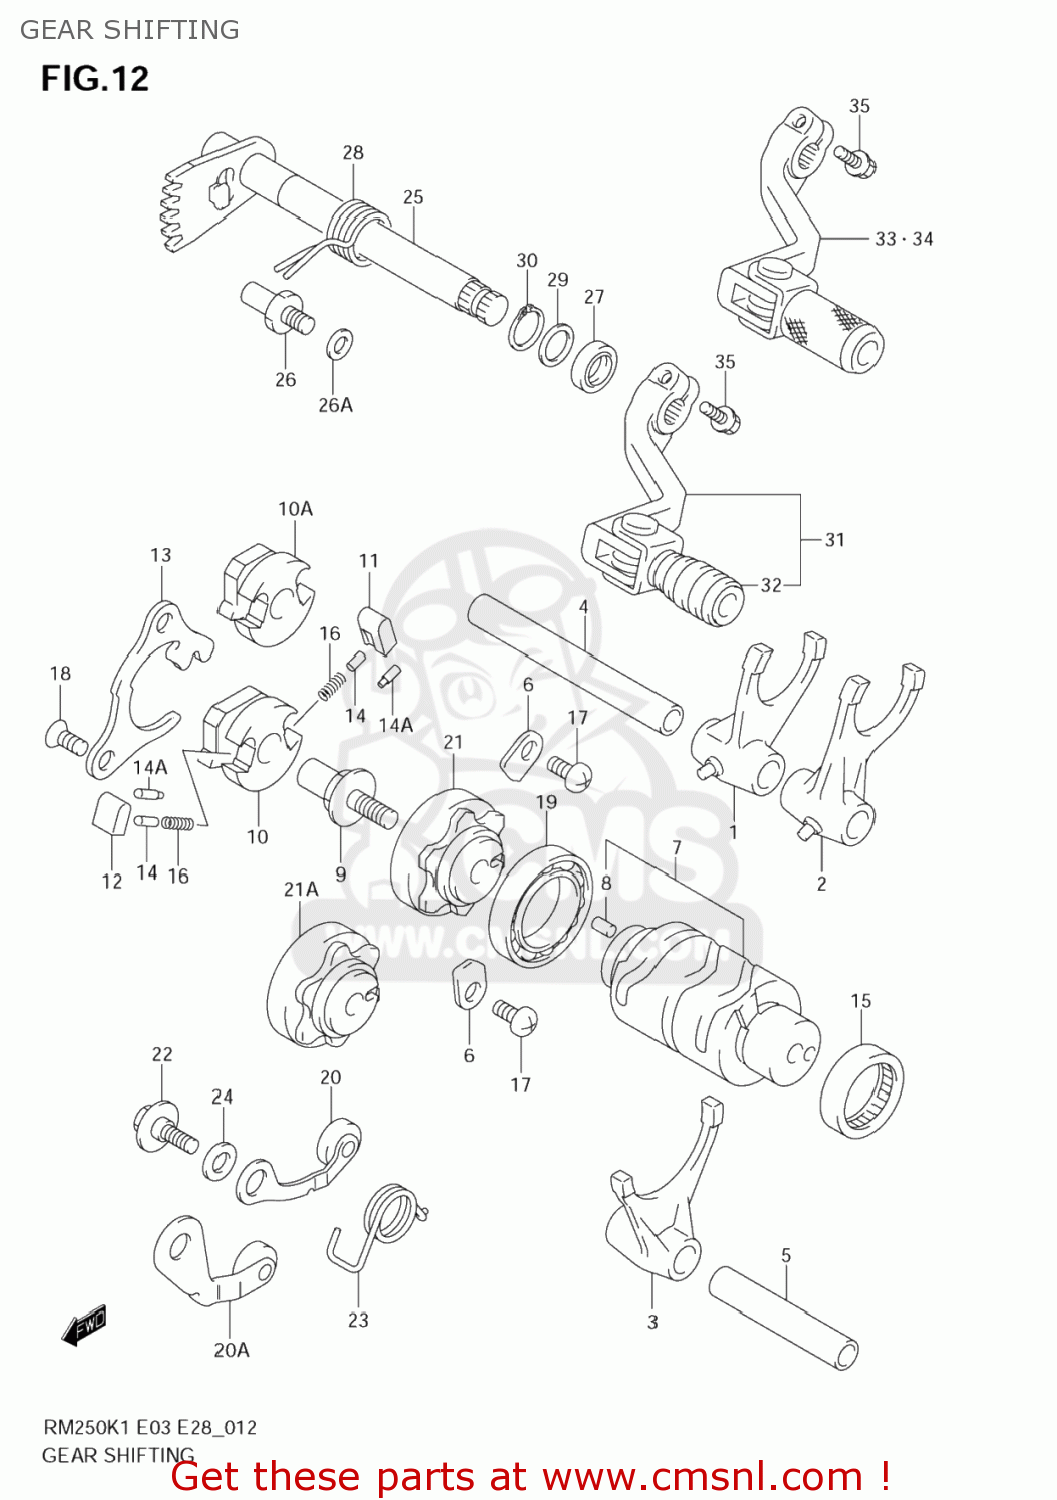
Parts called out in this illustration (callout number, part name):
1	FORK,GEAR SHIFT NO.1
2	FORK,GEAR SHIFT NO.2
3	FORK,GEAR SHIFT NO.3
4	SHAFT,GEAR SHIFT FORK
5	SHAFT,GEAR SHIFT FORK(L:60)
6	RETAINER
7	CAM,GEAR SHIFT
8	PIN
9	PIN,GEAR SHIFT CAM
10	GEAR,GEAR SHIFT CAM DRIVEN
10A	GEAR,GEAR SHIFT CAM DRIVEN
11	PAWL,GEAR SHIFT NO.1
12	PAWL,GEAR SHIFT NO.2
13	LIFTER,GEAR SHIFT PAWL
14	PIN(5X8)
14A	PIN
15	BEARING(25X32X12)
16	SPRING
17	BOLT(6X12)
18	SCREW
19	BEARING
20	STOPPER,SHIFT CAM
20A	STOPPER,SHIFT CAM
21	PLATE,SHIFT CAM STOPPER
21A	PLATE,SHIFT CAM STOPPER
22	BOLT(6X14.3)
23	SPRING
24	WASHER
25	SHAFT,GEAR SHIFT
26	STOPPER,GEAR SHIFT ARM
26A	SHIM(8.8X14X1)
27	SEAL,OIL(14X22X6)
28	SPRING
29	SHIM(14X20X1)
30	CIRCLIP
31	LEVER ASSY,GEA
32	RUBBER,GEAR SHIFT PEDAL
33	LEVER ASSY,GEAR SHIFT
34	LEVER ASSY,GEAR SHIFT
35	SCREW
